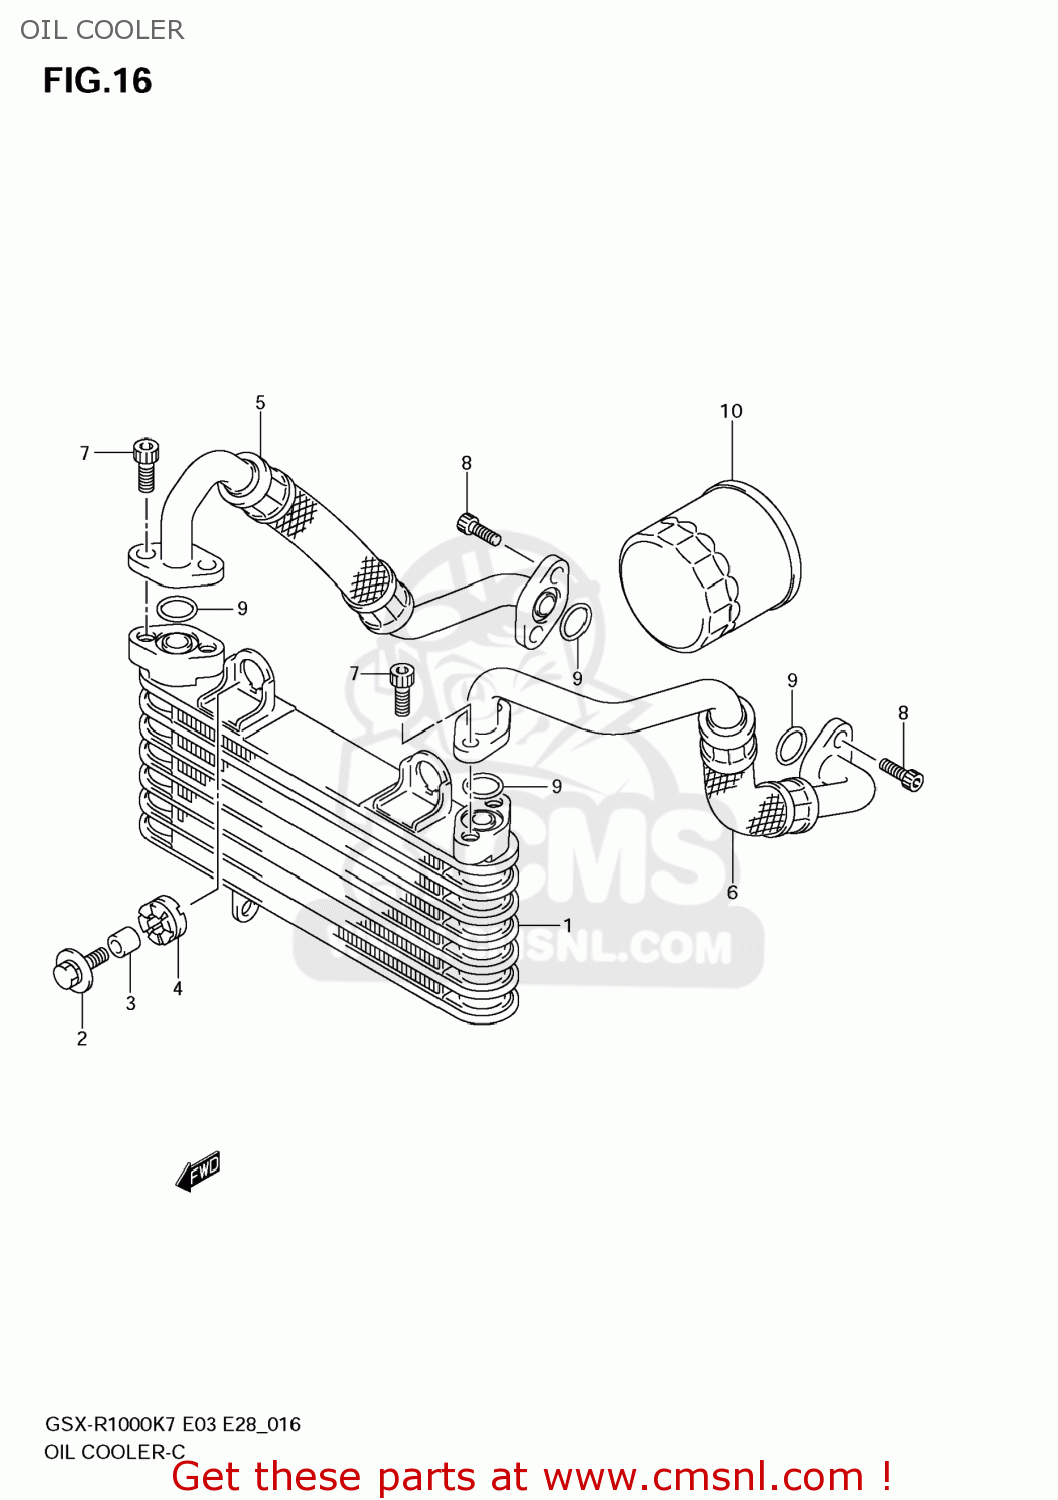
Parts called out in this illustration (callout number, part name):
1	COOLER ASSY,OIL
2	BOLT(6X25)
3	SPACER(6.5X10X10)
4	CUSHION
5	HOSE,OIL COOLER,R
6	HOSE,OIL COOLER,L
7	BOLT(6X20)
8	BOLT(6X16)
9	O RING(D:2.4,ID:16)
10	FILTER ASSY,EN
